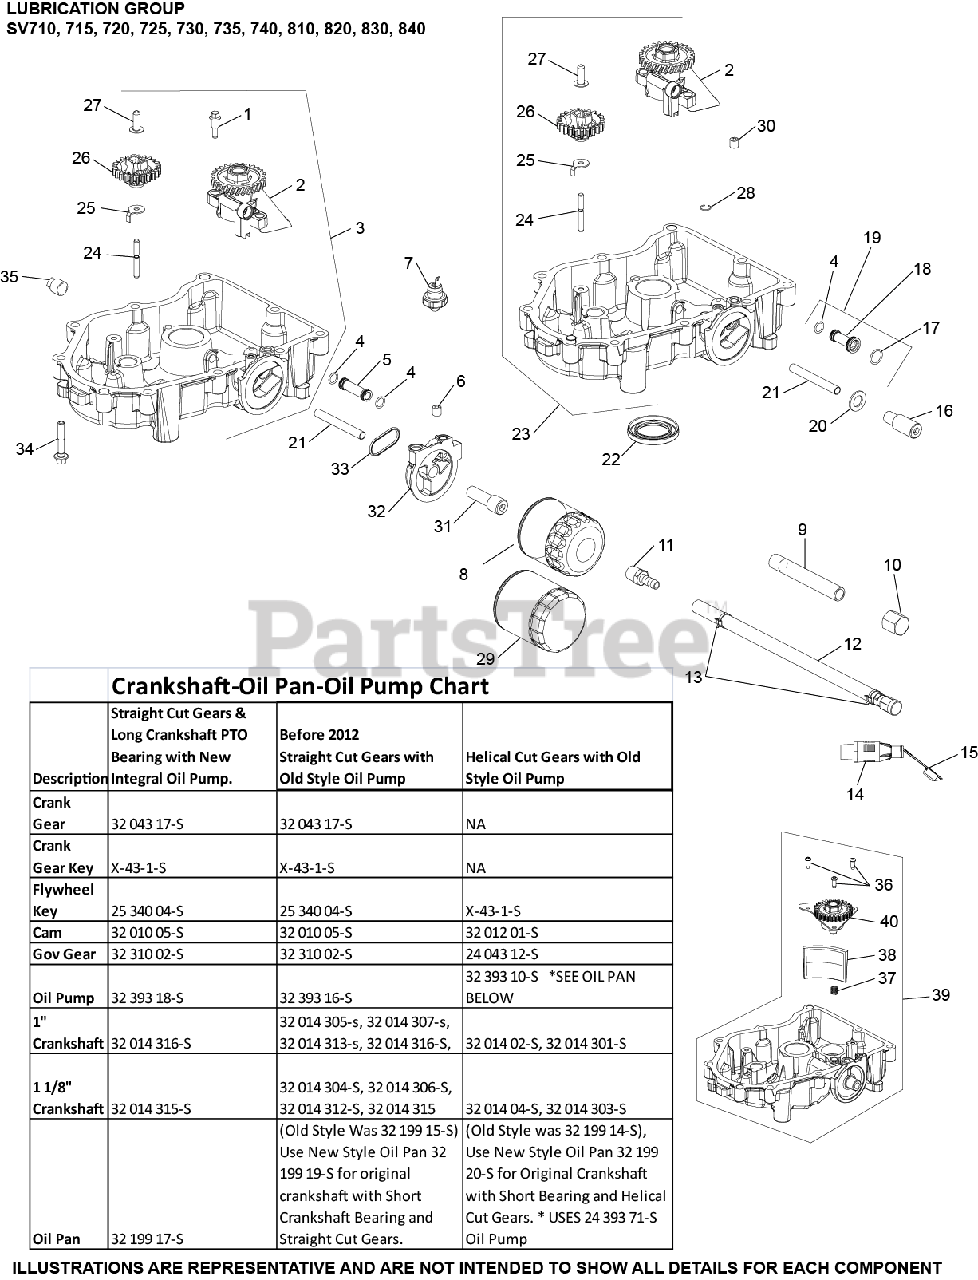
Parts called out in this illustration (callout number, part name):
2	PUMP, OIL ASSEMBLY - DISCONTINUED
4	O-RING, OIL PICK-UP
6	PLUG, CTSK PIPE 1/8"
8	OIL FILTER
16	NIPPLE, OIL FILTER - DISCONTINUED
17	O-RING
18	TUBE, OIL FEED
19	OIL FEED TUBE ASSEMBLY
20	WASHER, FLAT
21	TUBE, OIL FEED - FILTER TO PAN
22	SEAL, OIL
23	OIL PAN ASSEMBLY - (#3219920S)
24	SHAFT, GOVERNOR GEAR
25	TAB, LOCKING
26	KIT, GOVERNOR GEAR
27	PIN, GOVERNOR REGULATING
28	RETAINER, PIN - DISCONTINUED
30	PLUG, CTSK PIPE 1/8"
34	SCREW, FLG M8X1.25X45
35	PLUG, SQ HD PIPE 3/8"
36	SCREW, BUTTON HEAD
37	SPRING, COMPRESSION
38	SCREEN, OIL
39	PAN ASSEMBLY, OIL
40	PUMP ASSEMBLY, OIL
